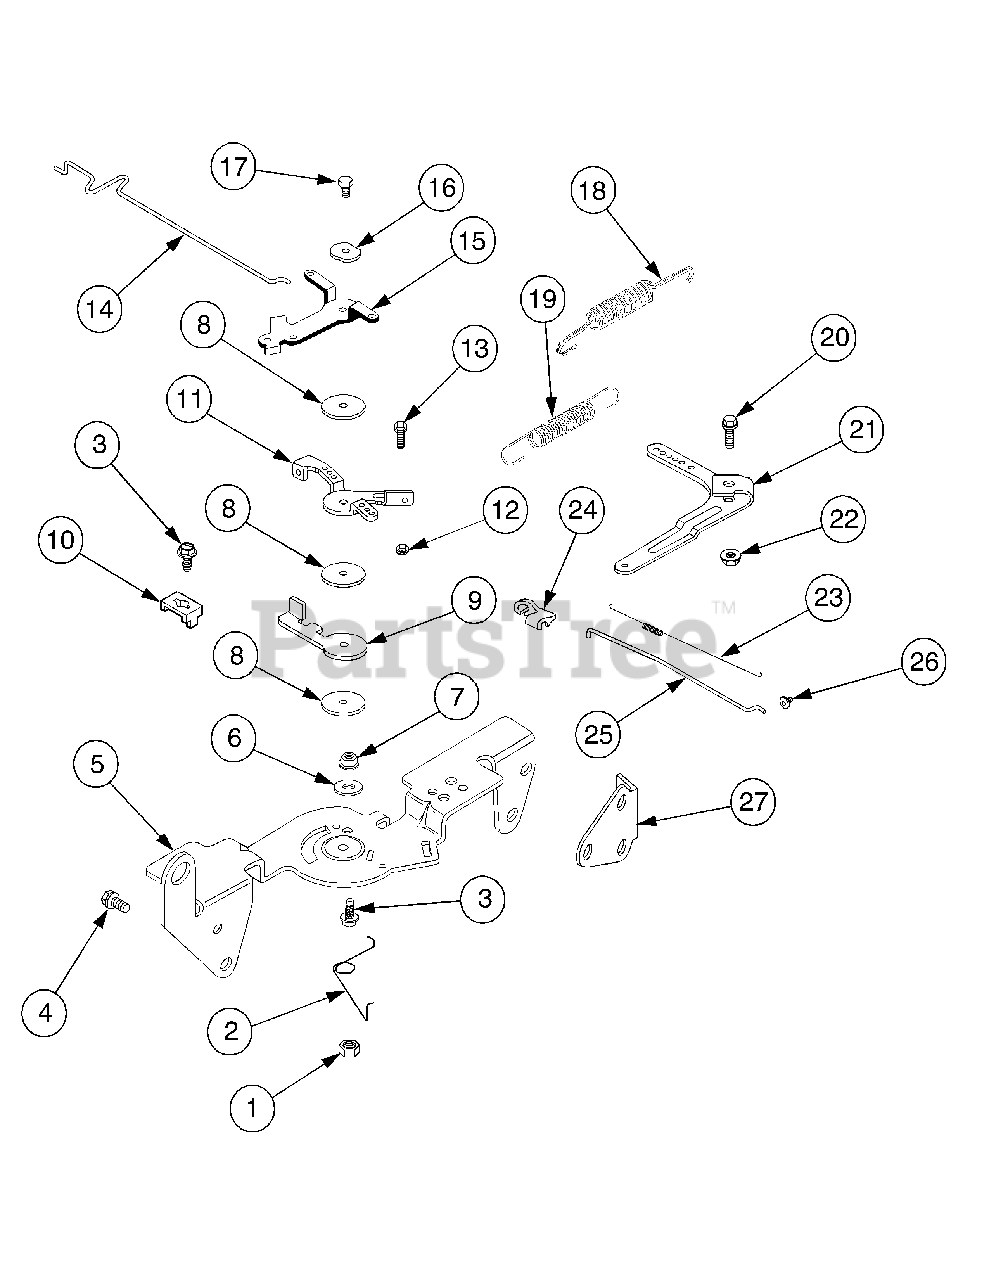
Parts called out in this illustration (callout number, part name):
1	Nut, Hex Lock M5 x 0.8
2	Spring, Choke Return
3	Screw, Hex Flange M5 x 0.8 x 16
4	Screw, Hex Flange M6 x 1.0 x 16
5	Bracket, Control
8	Washer , Plain 5.5mm
9	Lever, Throttle Actuator
10	Clamp, Cable
11	Lever, Throttle Control
12	Nut, Hex M4 x 0.7
13	Screw, Hex Cap M4 x 0.7 x30
14	Linkage, Choke
15	Lever, Choke
16	Washer, Spring 1/4"
17	Screw, Hex Flange M5 x 0,.8 x 20
18	Spring, Throttle Limiter
19	Spring, Governor
20	Screw, Round Hd. Square Neck
21	Lever, Governor
22	Nut, Hex Flange M6 x 1.0
23	Spring, Linkage
24	Bushing, Linkage Retaining
25	Linkage, Throttle
26	Bushing, Linkage Retaining
27	Bracket, Support
